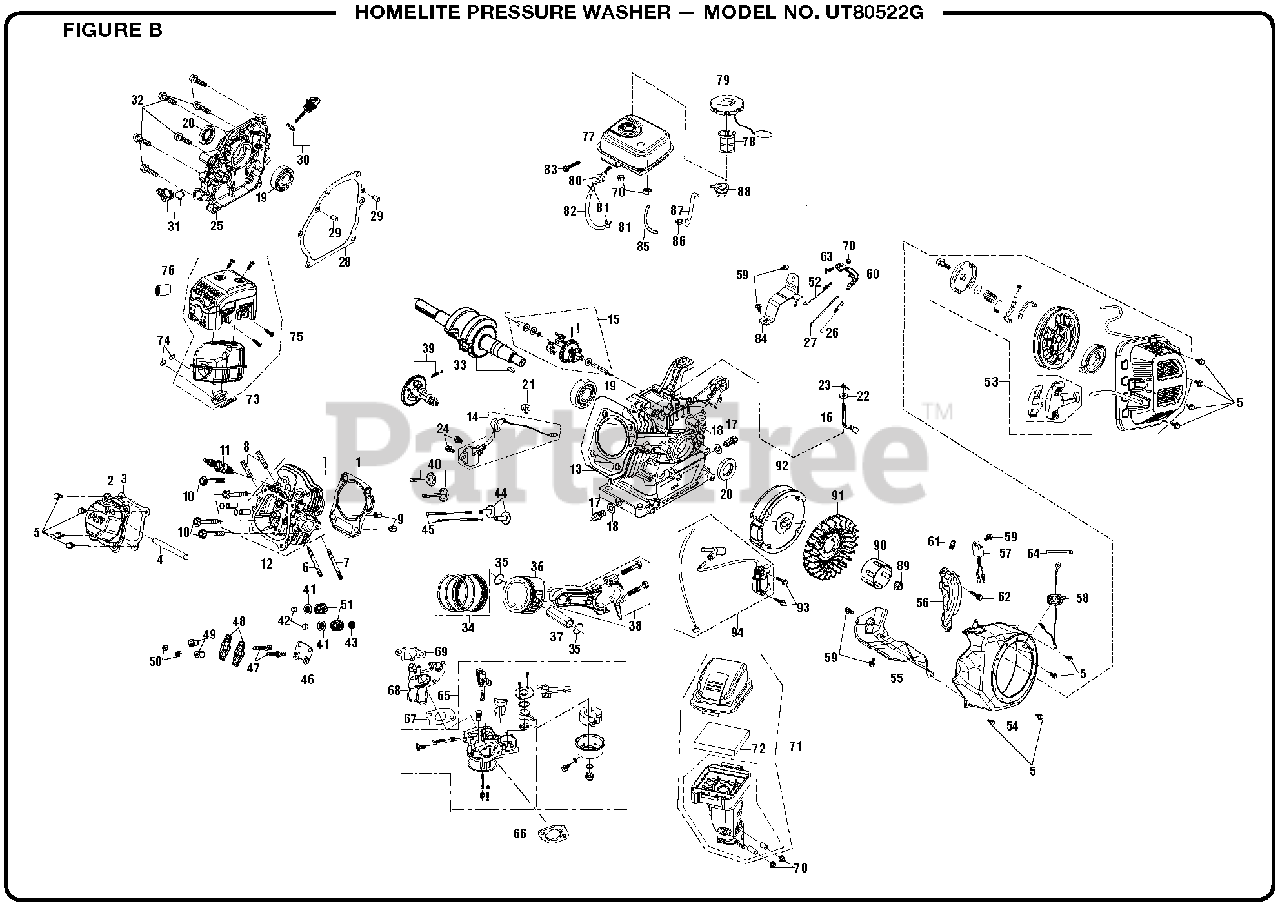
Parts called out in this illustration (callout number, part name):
1	Cylinder Head Gasket
2	Cylinder Head Cover Assembly
3	Cylinder Head Cover Gasket
5	Bolt (need size)
10	Bolt (Cylinder Head)
12	Cylinder Head Assembly
13	Crankcase Assembly
14	Engine Oil Sensor
15	Governor Gear Assembly
17	Drain Plug Bolt
19	Bearing
25	Crankcase Cover Assembly
26	Throttle Valve Return Spring
28	Crankcase Gasket
33	Crankshaft Assembly
35	Piston Pin Clip
36	Piston Assembly
39	Camshaft Assembly
41	Valve Spring Seat
46	Guide Plate Assembly
47	Valve Adjusting Bolt
49	Valve Adjusting Nut
52	Governor Spring
53	Recoil Starter Assembly
54	Shroud
55	Shroud (flasque de cylindre)
58	Switch Assembly
60	Governor Support Assembly
65	Carburetor Assembly
66	Air Cleaner Gasket
67	Carburetor Gasket
68	Carburetor Insulator Plate
69	Carburetor Insulator Gasket
70	Nut (need size)
72	Air Cleaner Element
73	Exhaust Outlet Gasket
74	Nut (need size)
75	Muffler Assembly
76	Catalyst Assembly
79	Fuel Tank Cover
80	Fuel Filter Assembly
84	Throttle Control Assembly
88	Fuel Tank Vapor Vent
92	Flywheel Assembly
